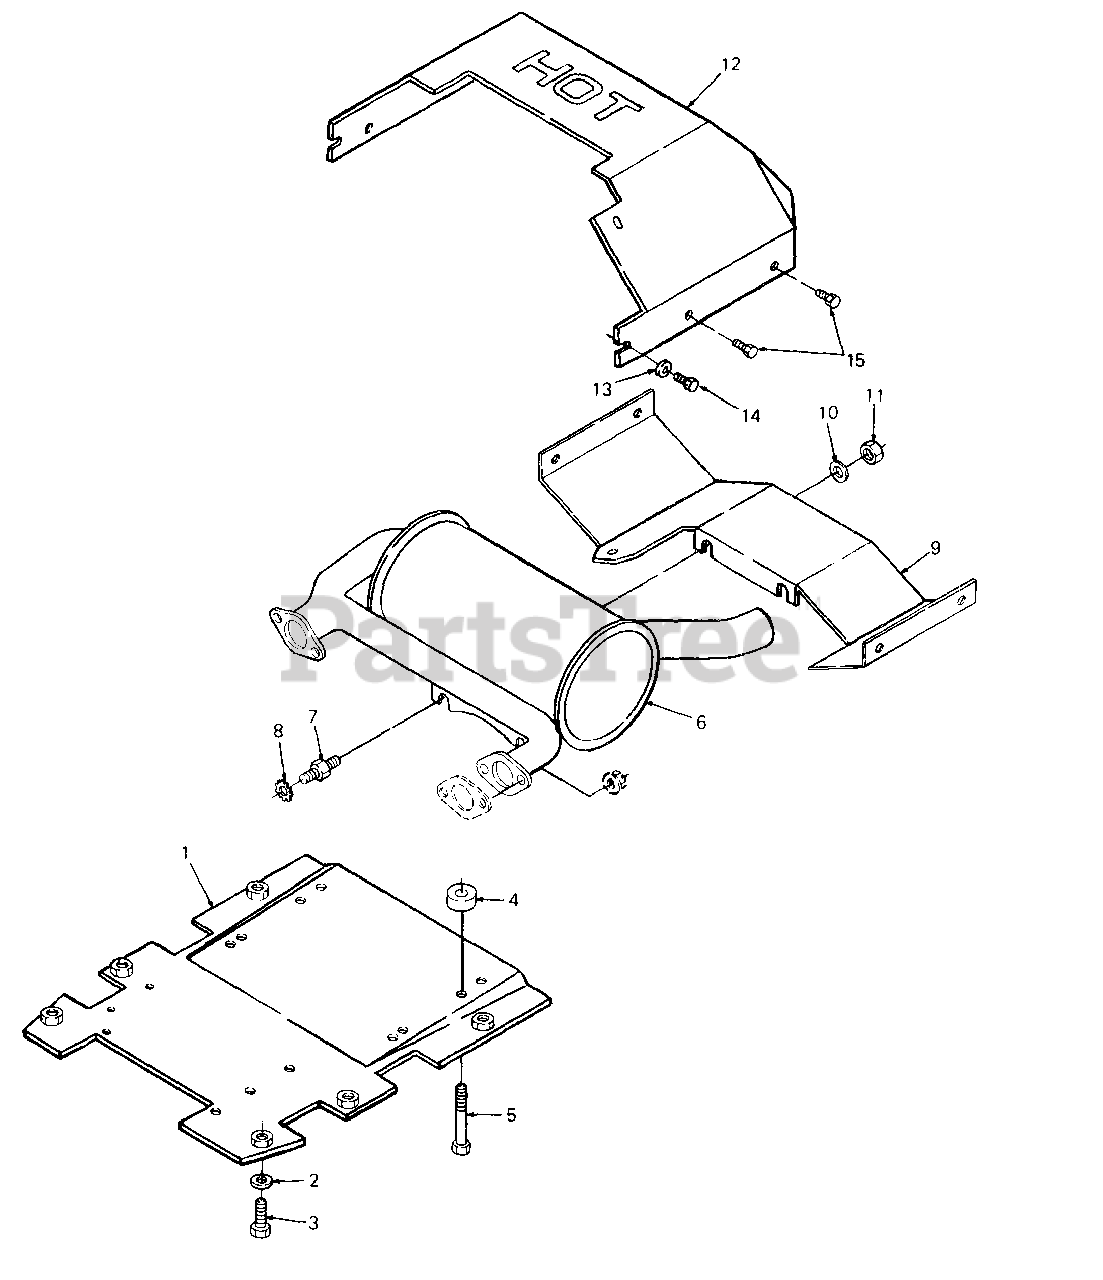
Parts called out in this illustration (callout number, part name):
3	Belt, Patch, 3/8-16 x 1.0 Lg
4	Spacer, .423 x 1.0 x .469 Lg
5	Bolt, Patch, 3/8-16 x 2.25 Lg
7	Stud, 7/16-14 UNC-2A Thd
8	Washer, External Lock, .45 x .75 x .03 Thk
11	Nut, Hex, 7/16-14 GR5
12	Duct, Engine
13	Washer, Flat, .281 x .50 x .063 Thk
14	Bolt, Hex, M6-1.0 x 10 MM Lg GR5
15	Screw, Hex Wash Hd Tapp, #10 x .50 Lg
